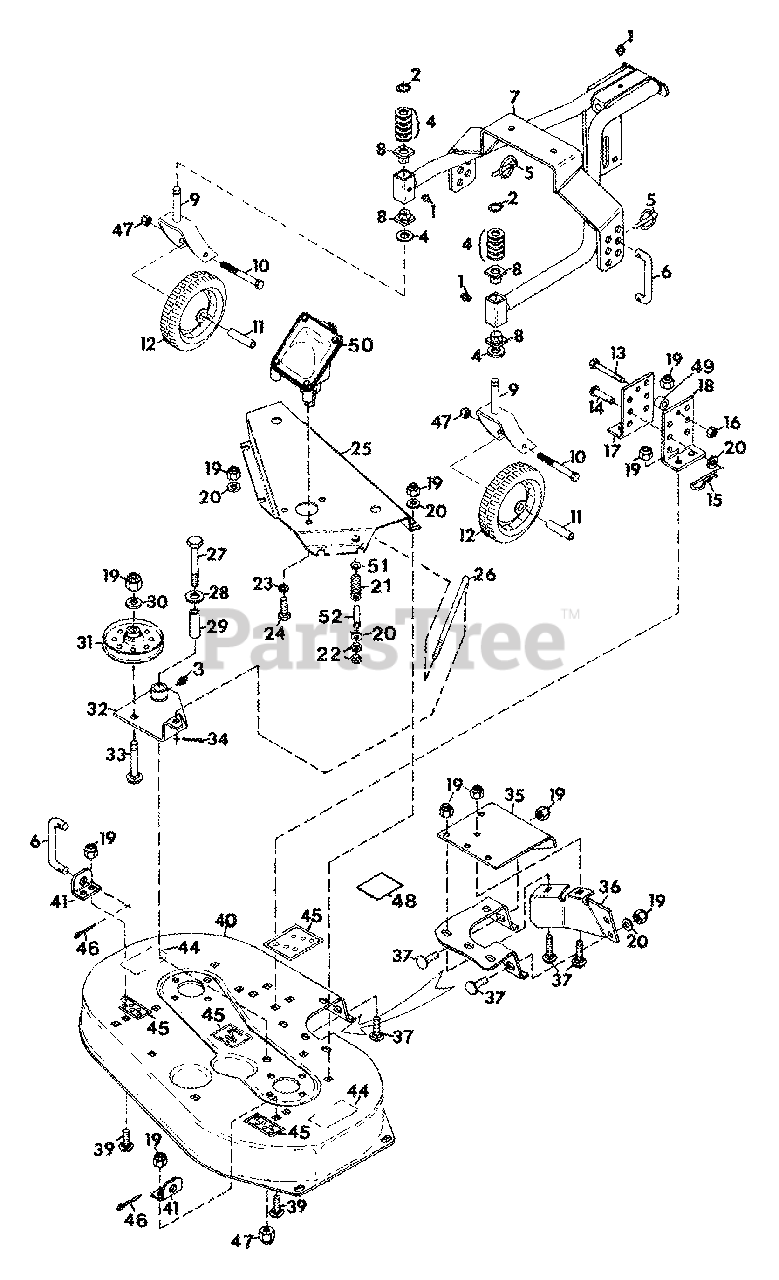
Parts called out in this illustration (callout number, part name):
1	Fitting-Lube .25-28 x .256
2	Ring-Retaining-Internal .750 x .042
3	Fitting-Lube .25-28 x .256
4	Washer-Flat-Steel .813 x 1.370 x .100
5	Pin-Klik 1.000 x .188 x 1.25
6	Rod, Adjusting
7	Weldment, Support
8	Bushing-Flange .610 x 1.200 x 1.04 x .190
9	Weldment, Caster
10	Bolt-Hex .50-13 x 5.00 Grade 5
11	Spacer .532 x .748 x 3.34
12	Wheel Hub 3.25 x .75
13	Bolt-Hex .25-20 x 1.25 Grade 5
14	Pin, Clevis .375 x .948
15	Pin-Hair Internal .08 x .18 x 1.18
16	Nut-Locking-Nylon .25-20
17	Bracket, Rear Support
18	Bracket, Rear Support
19	Nut-Locking-Nylon .38-16
20	Washer-Flat-Steel .406 x .812 x .065
21	Spring-Compression .125 x .78 x 1.00
22	Nut-Hex .375-24
23	Washer-Locking .50 x .125 Regular
24	Bolt-Hex .50-13 x 1.00 Grade 5
25	Guard, Belt
26	Rod, Idler 40 inch Mower
27	Bolt-Hex .50-13 x 2.00 Grade 5
28	Washer-Flat-Steel .531 x 1.06 x .095
29	Spacer .516 x .874 x .998
30	Washer-Flat-Steel .438 x 1.00 x .083
31	Pulley-Idler 4.50 x .380
32	Weldment, Idler Pivot
33	Bolt-Round Head Square Neck .38-16 x 2.00 Grade 5
34	Pin-Cotter .06 x 1.00
35	Shield, Discharge
36	Shroud, Blade
37	Bolt-Round Head Square Neck .38-16 x 1.0
39	Bolt-Round Head Square Neck .38-16 x .75 Grade 5
40	Deck, 40 Inch Mower
41	Bracket, Mower Support
44	Decal, Danger
45	Decal Set, 40" Mower
46	Pin-Cotter .12 x .75
47	Nut-Locking-Nylon .50-13
48	Decal, Warning
49	Spacer .277 x .375 x .440
50	Assembly-Gearbox
51	Washer
52	Sleeve, Rod
